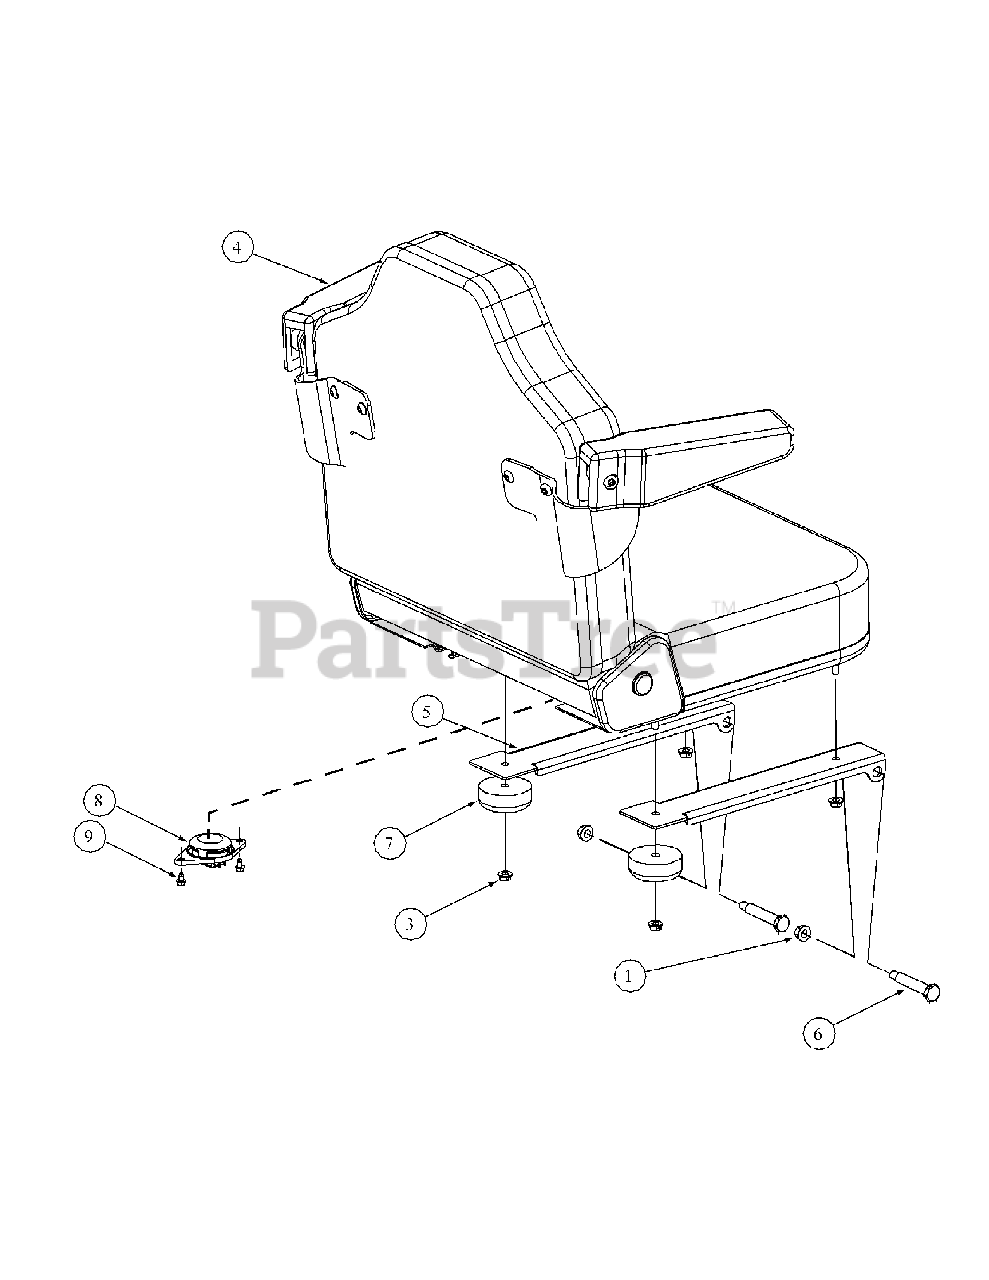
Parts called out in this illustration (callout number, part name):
1	Nut, Hex 3/8-16 Flange Lock
3	Lock Nut, Hex Flange, 5/16-18
4	Adjustable Seat
5	Mounting Bracket, Seat
6	Shoulder Screw, .50x2.345, 3/8-16
7	Grommet, 2.5 OD x 1.0 Long
8	Seat Switch
9	Screw, TT, 1/4-20, .500, Hex
